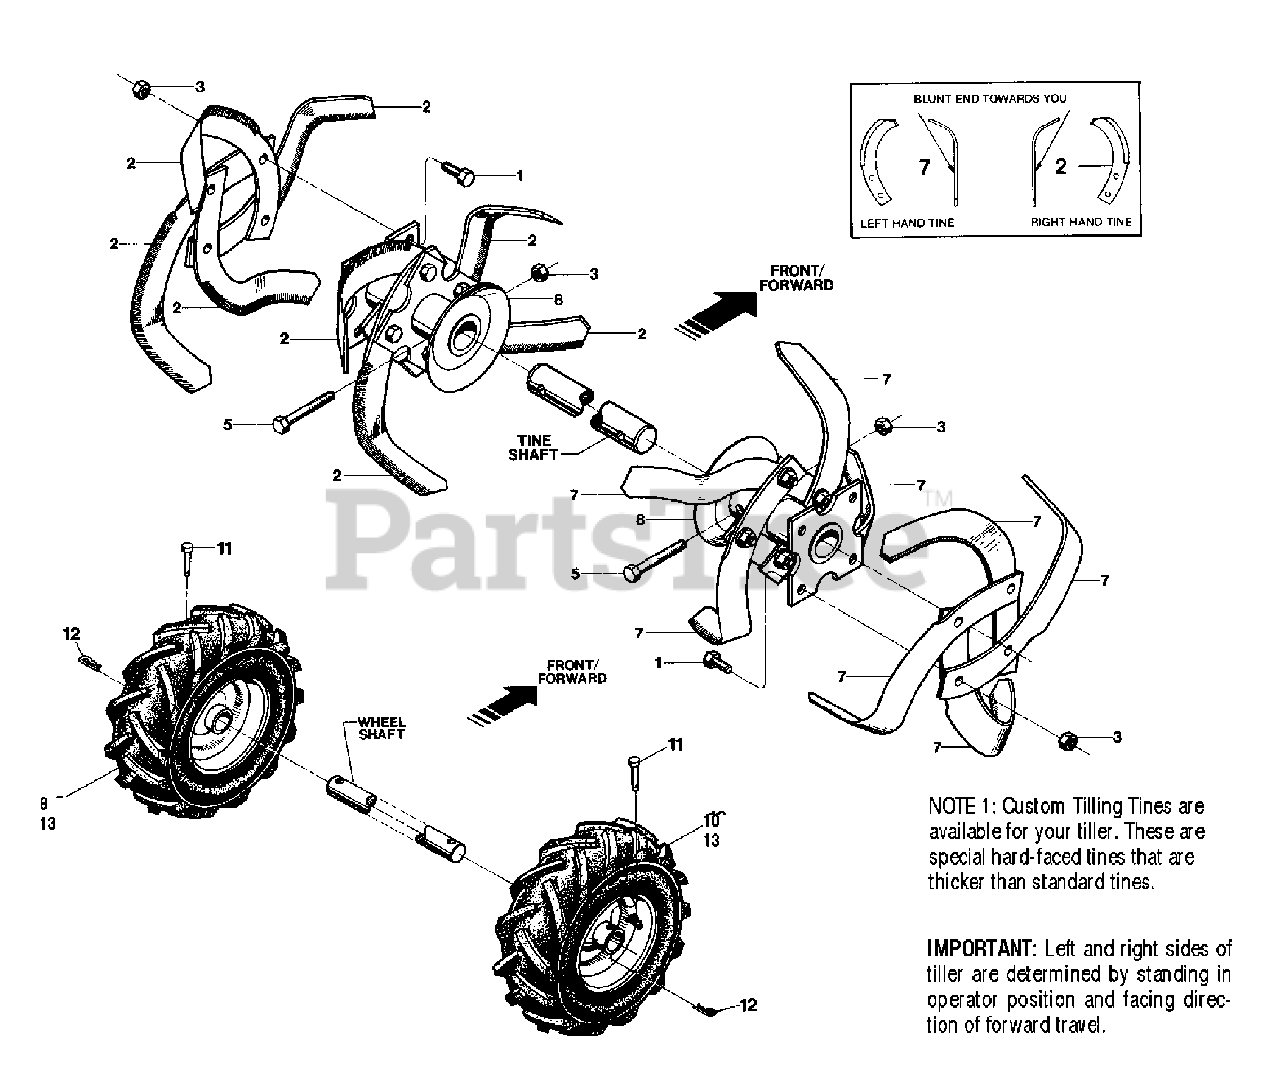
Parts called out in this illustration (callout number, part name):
1	Hex Hd. Screw, 3/8-16 x 1-1/4
2	Bolo Tine-single,
3	Hex Locknut, 3/8-16
5	Hex Hd. Screw, 3/8-16 x 2, Grade 8
7	Bolo Tine-single,
8	Tine Holder
9	Wheel and Tire Assy left side, 4.10 x 6 tire on 6" wheel
10	Wheel & Tire Assy right side, 4.10 x 6 tire on 6" wheel
11	Clevis Pin, .312 x 1-3/4
12	Hitch Pin
13	Wheel and Tire Assembly
